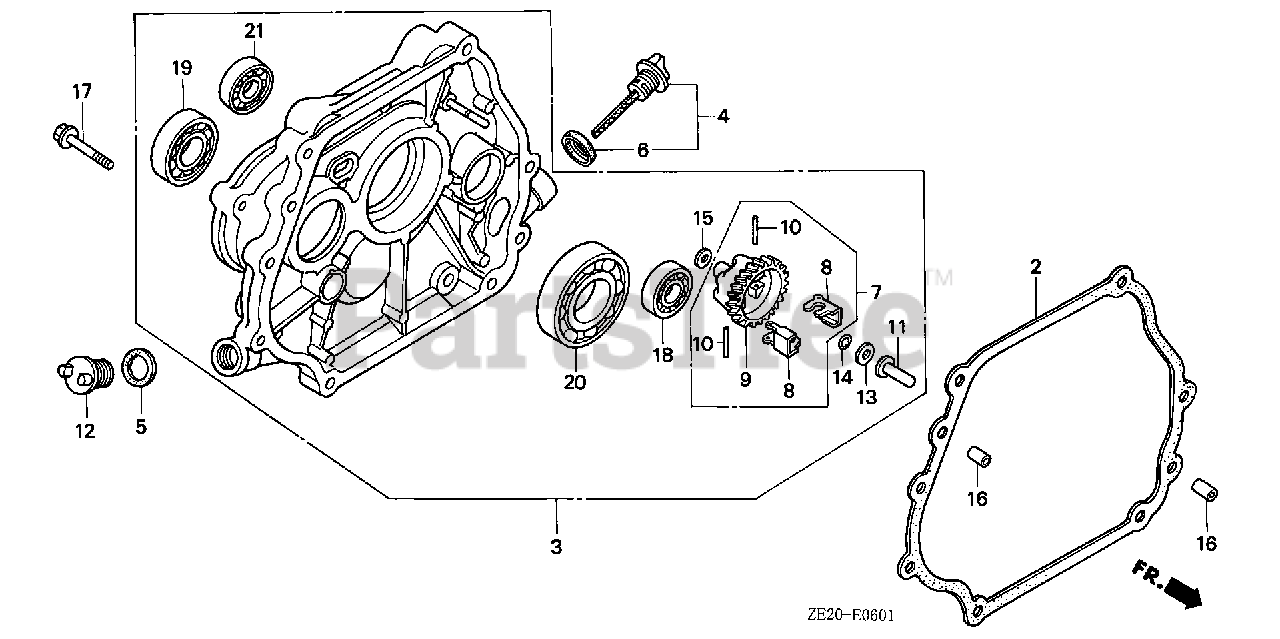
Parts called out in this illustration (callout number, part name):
2	GASKET, CASE COVER
3	COVER ASSY., CRANKCASE
4	CAP ASSY., OIL FILLER
5	GASKET, OIL FILLER CAP
6	GASKET, OIL FILLER CAP
7	GOVERNOR ASSY. (NOT AVAILABLE)
7	GOVERNOR ASSY.
8	WEIGHT, GOVERNOR
9	HOLDER, GOVERNOR WEIGHT (NOT AVAILABLE)
9	HOLDER, GOVERNOR WEIGHT
10	PIN, GOVERNOR WEIGHT
11	SLIDER, GOVERNOR
12	CAP, OIL FILLER
12	CAP, OIL HOLE
13	WASHER (6X16)
14	CLIP, GOVERNOR HOLDER
15	WASHER, PLAIN (6MM)
16	PIN, DOWEL (8X12)
16	PIN A, DOWEL (8X12)
17	BOLT, FLANGE (8X35)
18	BEARING, RADIAL BALL (6202)
19	BEARING, RADIAL BALL (6204)
20	BEARING, RADIAL BALL (6206)
